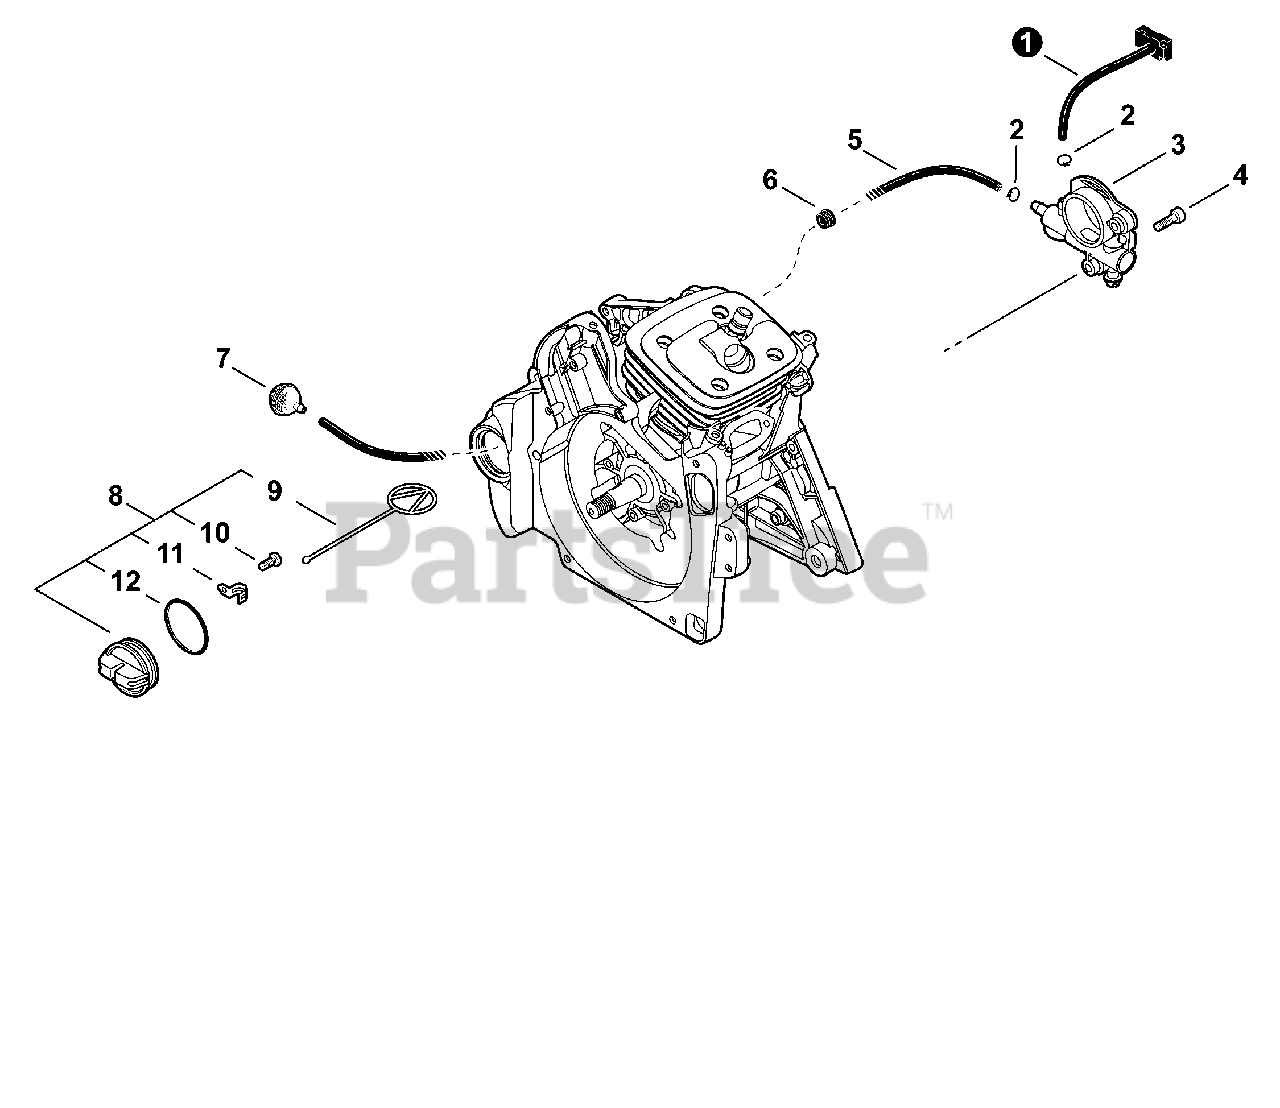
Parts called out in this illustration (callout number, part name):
1	PIPE, OIL
2	CLIP - 6
3	AUTO-OILER ASY
4	SCREW - 4×12
5	PIPE - 3×6×210 -- BLACK
6	GROMMET
7	FILTER, OIL
8	CAP ASY
9	CONNECTOR, CAP
10	SCREW - 3×8
11	RETAINER, CONNECTOR
12	O-RING - 28
